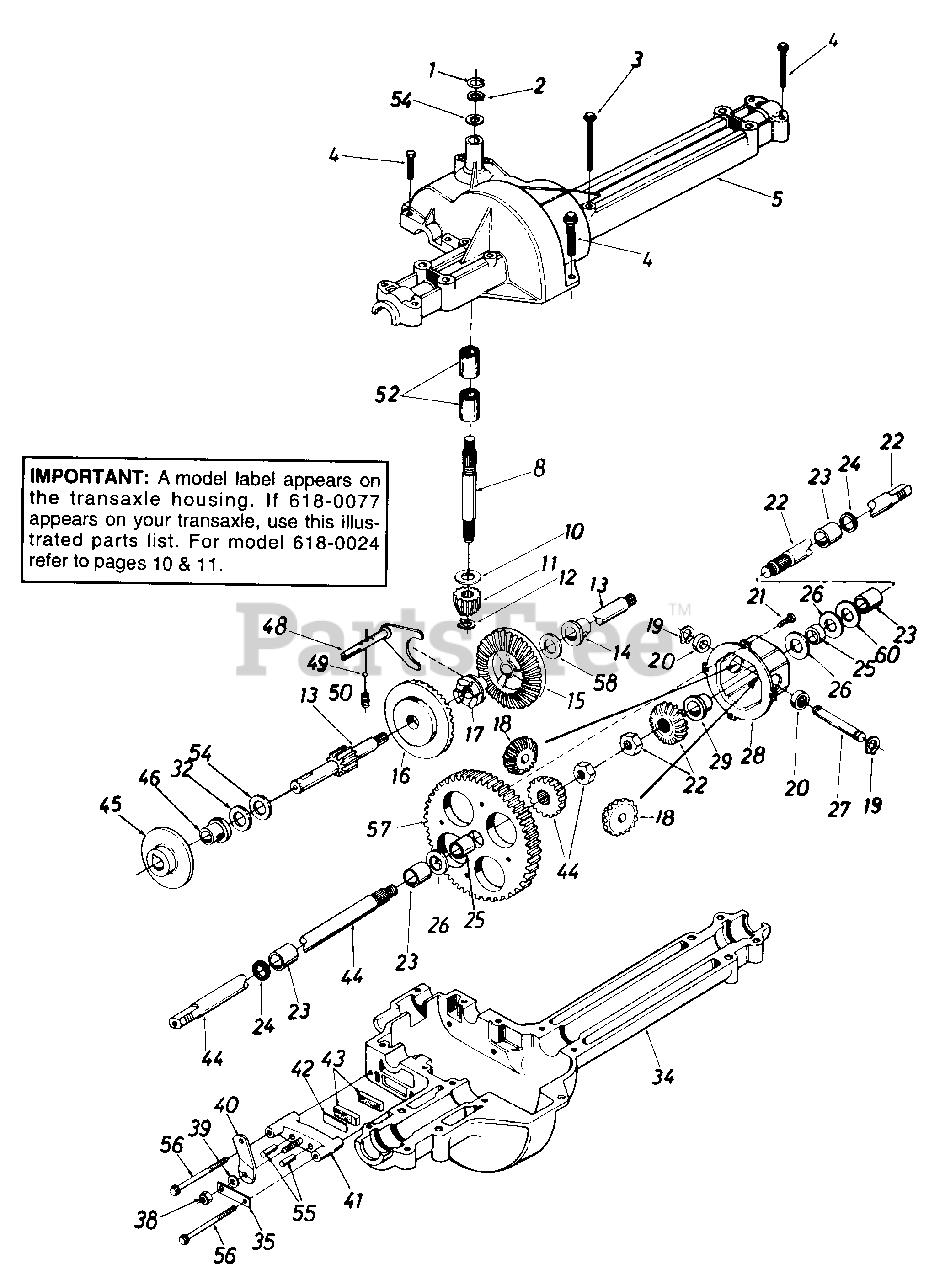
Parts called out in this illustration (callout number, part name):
2	Retaining - Ring
3	Hex Bolt 1/4-20 x 1.75" Lg.
4	Hex Tap Scr. 1/4-20 x 1.25" Lg.
5	Upper Housing
10	Thrust Washer 5/8" I.D. x 1.25" O.D.
11	Pinion Input 14T
12	Retaining Ring
13	Drive Shaft - L.H. Brake
14	Flange Brg. 5/8" I.D. x 3/4" Lg.
15	Bevel Gear 42T Small I.D.
16	Bevel Gear 42T Large I.D.
17	Clutch Collar
18	Miter Gear 15T (H.D.)
19	Retaining Ring
20	Thrust Bearing
21	Pan Head Scr. 1/4-20 x .50" Lg. w/Patch
22	Axle R.H. Ass'y.
23	Sleeve Bearing 3/4" I.D. x 1.0" Lg.
24	Oil Seal 3/4" I.D.
25	Axle Spacer
26	Fl-Wash. .760" I.D. x 1.5" O.D.
28	Differential Can Ass'y.
32	Thrust Wash. 5/8" I.D. x 1" O.D. x .025" Thk.
34	Lower Housing
35	Anti-Rotation Brkt.
38	Hex Nut 5/16-24 Thd.
39	Fl-Wash. .344" I.D. x .875" O.D.
40	Actuating Arm
41	Brake Yoke
42	Puck Plate
43	Brake Puck
44	Axle L.H. Ass'y.
45	Brake Disc
46	Flange Bearing 5/8" I.D. x 15/16" Lg.
48	Shift Fork Ass'y.
49	Ball Detent.250" Dia.
50	Spring Detent
52	Needle Brg. 5/8" I.D. x 1/2" Lg.
54	Fl-Wash. 5/8" I.D. x 1" O.D. x .020 Thk.
55	Actuating Pin 5/16" Dia.
56	Hex Wash Hd. Self-Tap Scr. 1/4-20 Thd.
57	Differential Gear 58T
58	Fl-Wash. 5/8" I.D. x 1" O.D. x .020 Thk.
60	Fl-Wash. .76" I.D. x 1.5" O.D. x .010" Thk.
